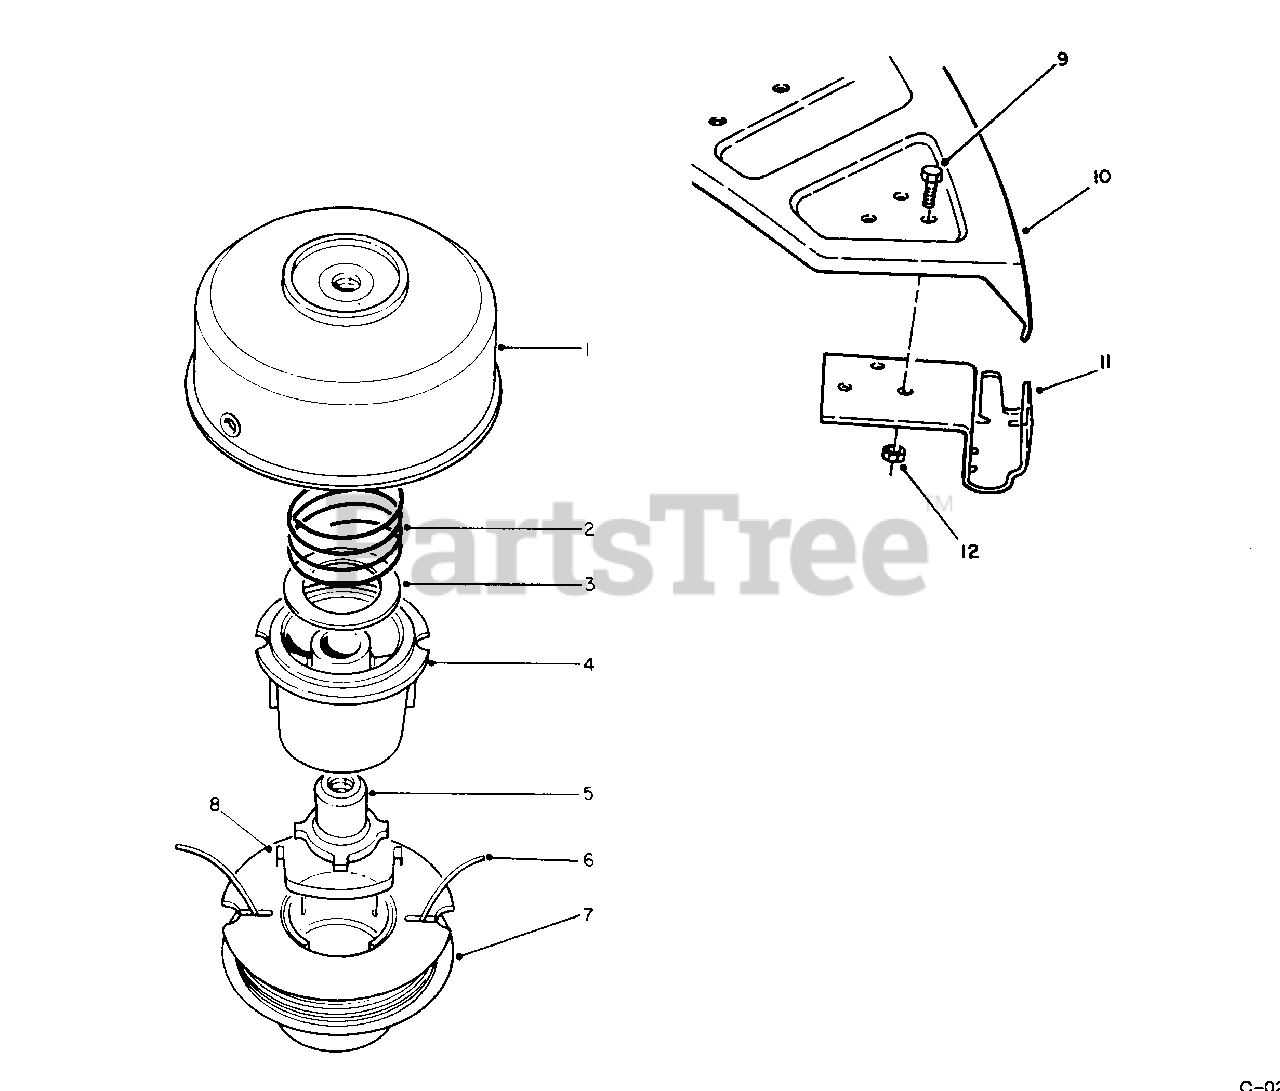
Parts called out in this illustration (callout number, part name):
1	Drum Assembly w/Eyelet
4	Spool Core
5	Driver L.H.
6	Line-Cutting .08 Dia. 38'
7	Spool Prewound (Incl. Ref. #8)
8	Saddle-Spool Cap
9	Screw Optional
10	Shield-Grass (Optional)
11	Bracket & Knife Blade Assembly (Optional)
12	Nut-Lock (Optional)
